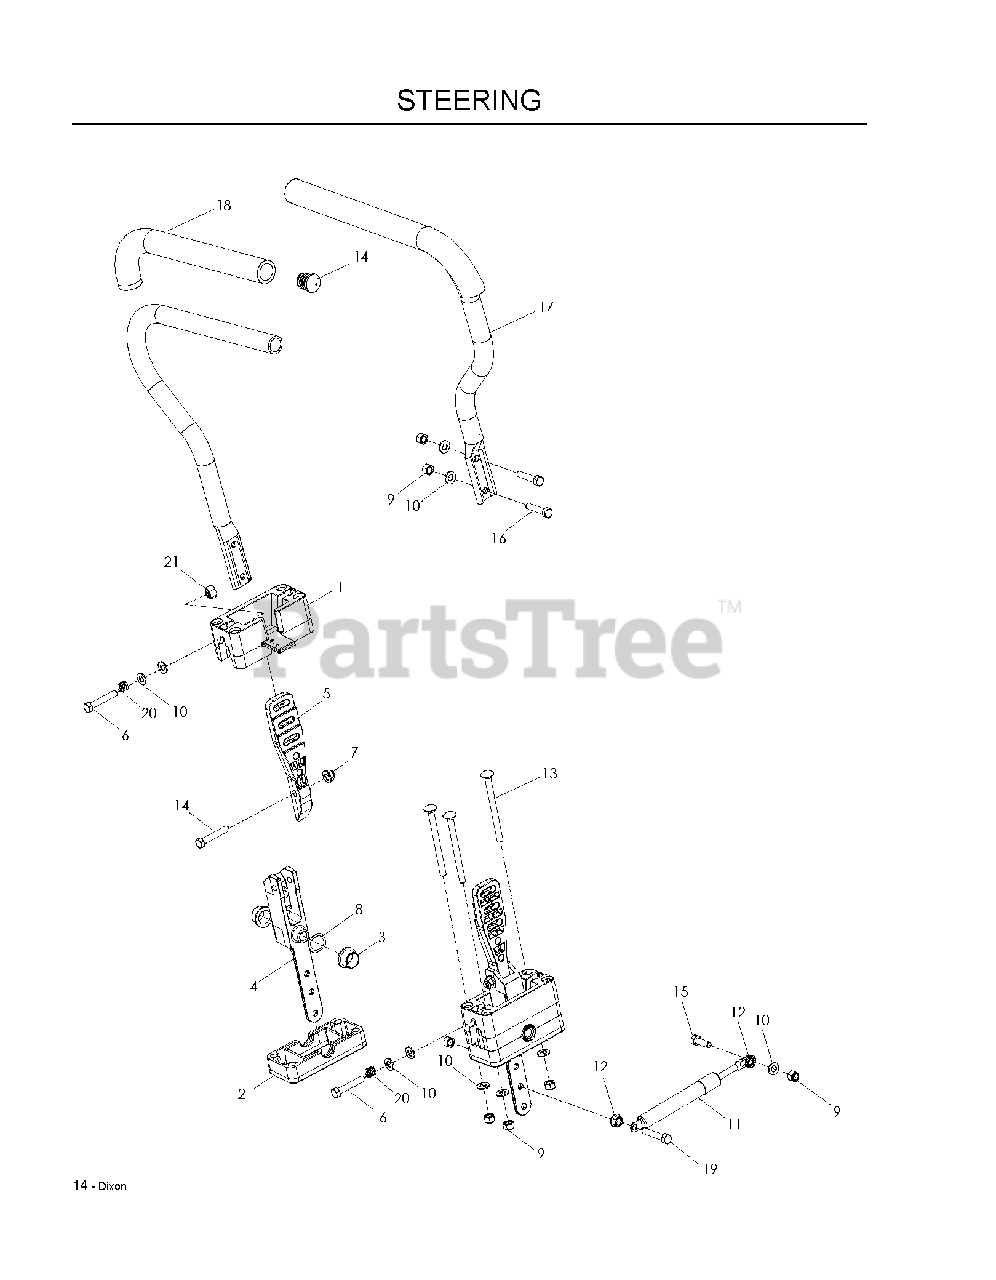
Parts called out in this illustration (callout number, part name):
1	BLOCK, UPPER
2	BLOCK, LOWER
3	BEARING, FLANGE
4	PIVOT.SECTION.DRIVE.CONTROL
5	MOUNT, DR CNTRL HANDLE
6	HCS 5/16-18X1-3/4 TPBLT
7	5/16-18 NYLOC FLANGE NUT
8	WASHER, .825 X 1.087, WAVE
9	NUT 5/16 NYLOC
10	FLAT WASHER 5/16 SAE
11	DAMPENER
12	NUT 5/16C WHIZ
13	RHSNB 5/16-18 X 4 GR 5 ZD
14	END PLUG 15/16` (BLACK)
15	HCS 5/16C X 1
16	CAPSCREW 5/16 X 1/1/2 HEX HEAD
17	ASSEMBLY, DRIVE LEVER
18	GRIP, FOAM (GROUND) 15
19	HCS 5/16C X 1 3/4
21	NUT 5/16C HEX
